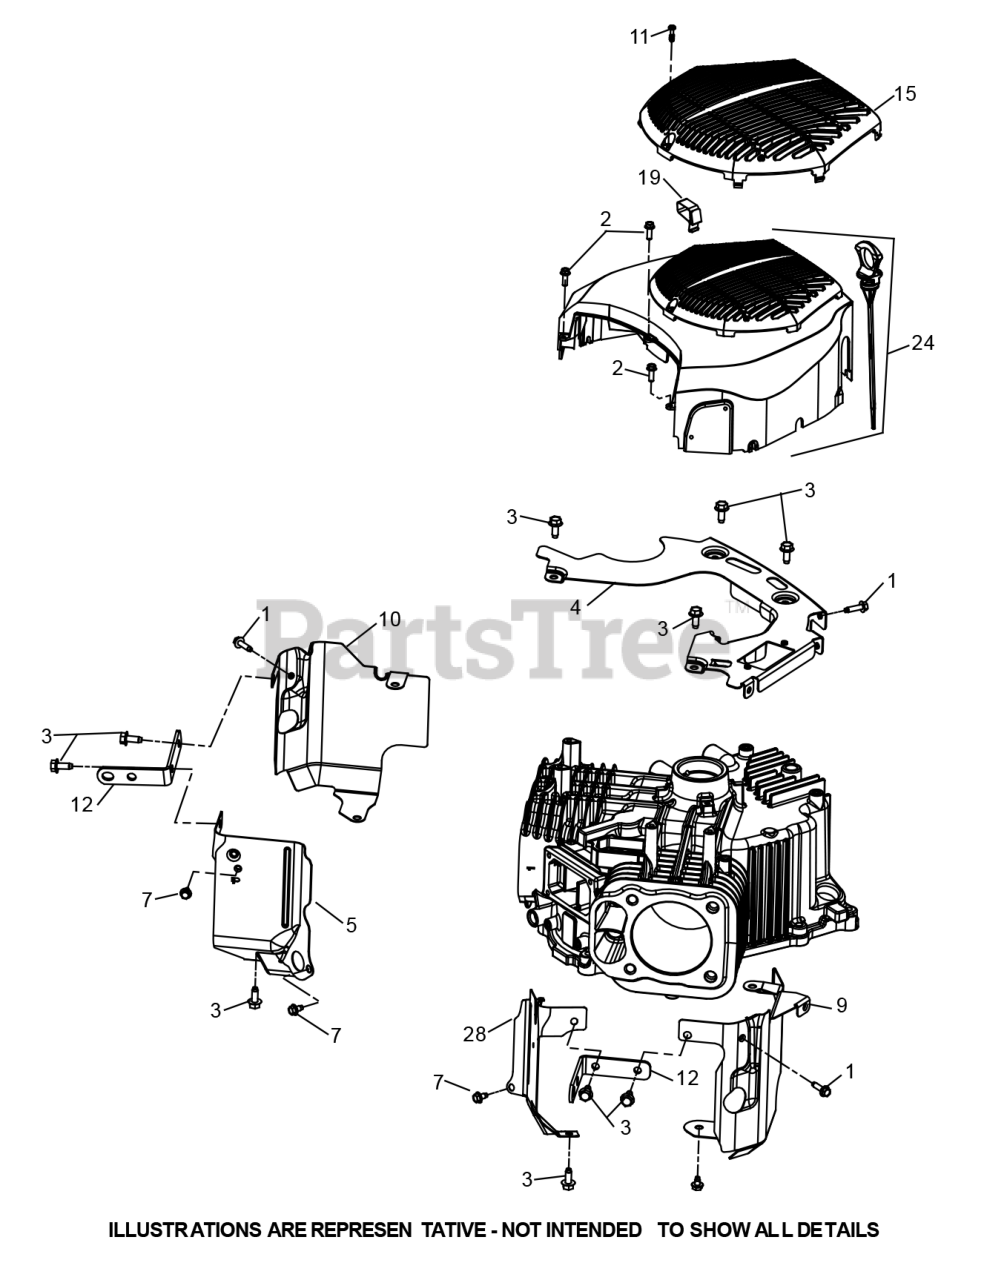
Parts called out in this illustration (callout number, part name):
1	THREAD FORMING SCREW
3	SCREW-THREAD FORMI
4	PLATE-BACKING
5	VALLEY BAFFLE-# 1
9	BAFFLE-LEFT BARREL
10	BAFFLE-RIGHT BARRE
11	SCREW- M5-2.42 (PT
12	STRAP-LIFTING
19	BLOWER HOUSING CLIP
24	BLOWER HOUSING KIT
28	VALLEY BAFFLE #2
